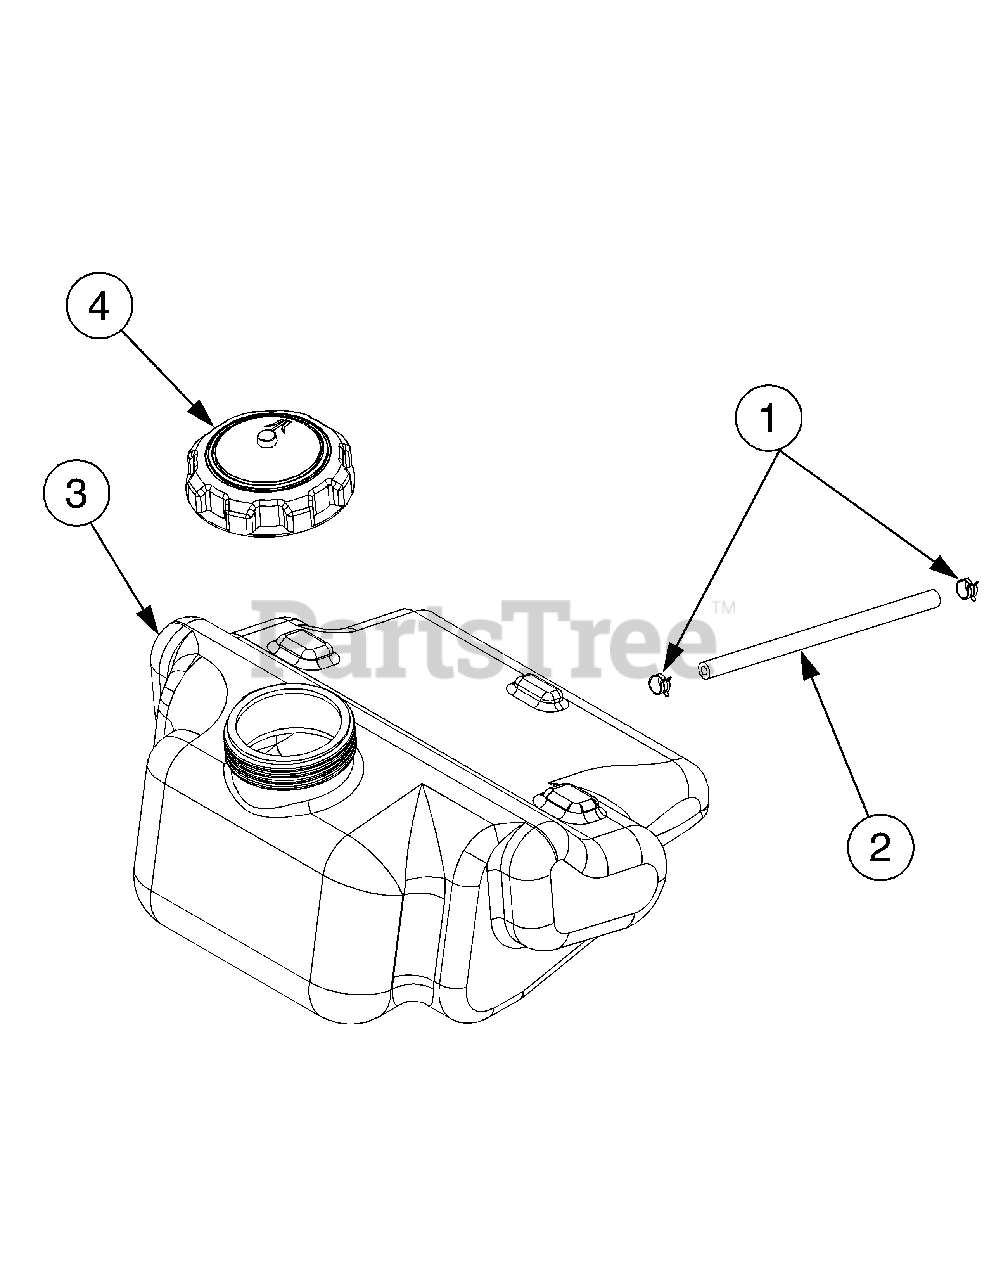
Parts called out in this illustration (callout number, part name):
1	Clamp, Hose
2	Line, Fuel, 72"
3	Tank, Fuel
4	Cap, Fuel
